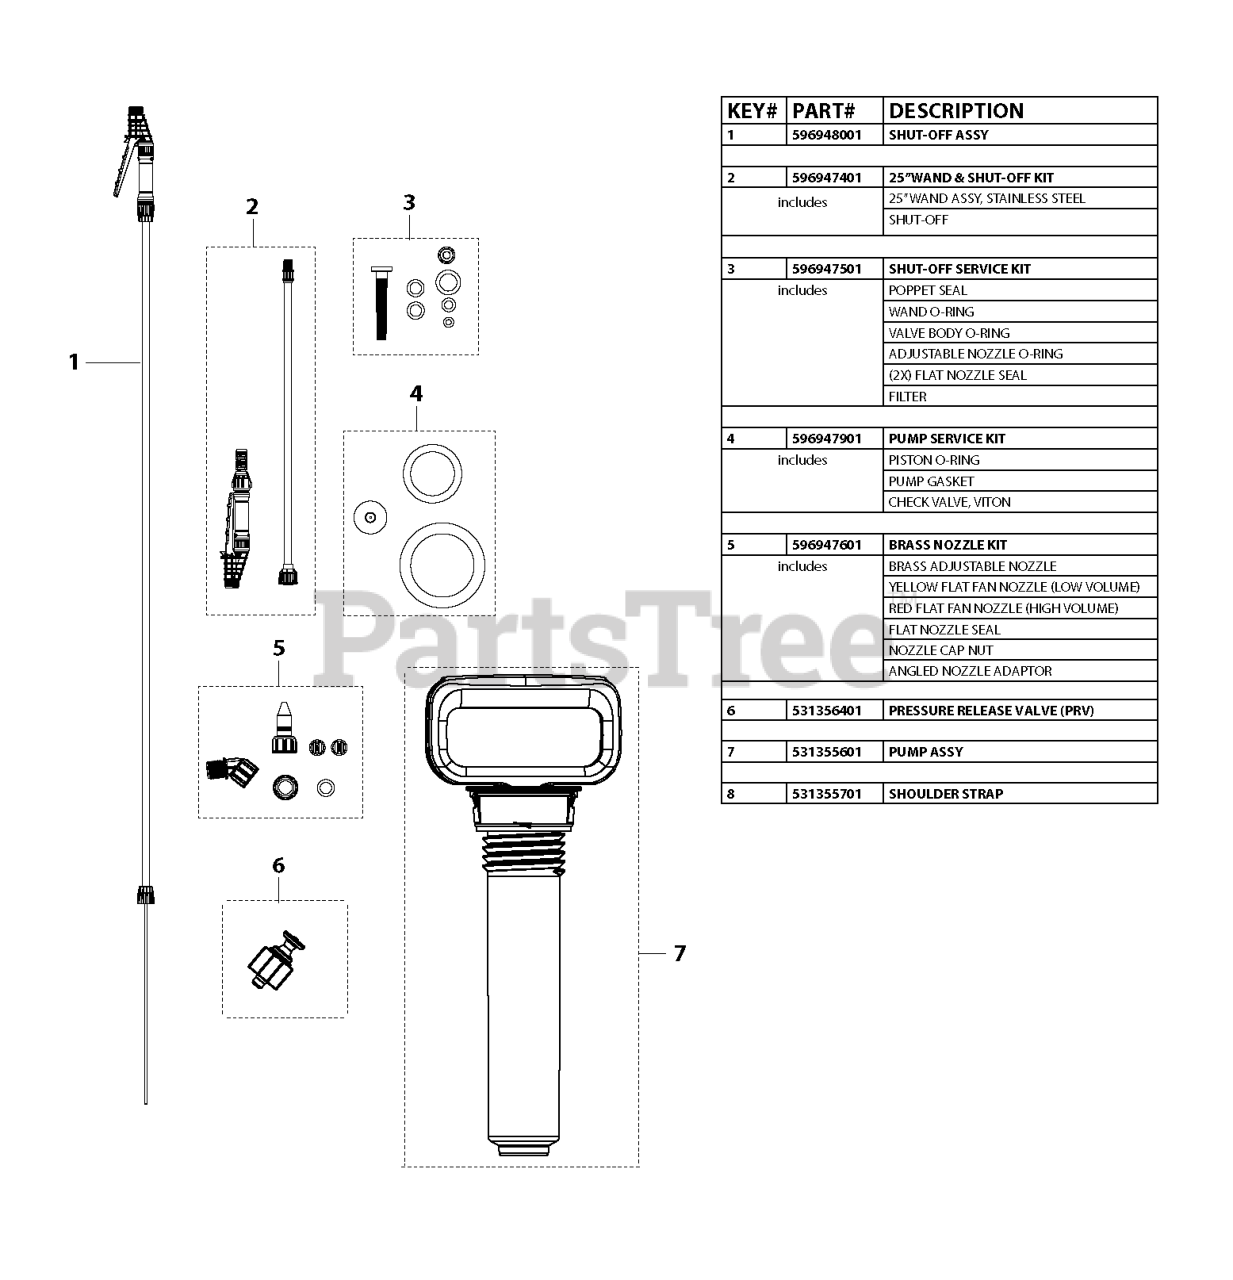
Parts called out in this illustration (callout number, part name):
1	2G SPRAYER SHUTOFF/HOSE ASSY
2	SPRAYER WAND/SHUTOFF KIT
3	SPRAYER SHUTOFF SERVICE KIT
4	2G SPRAYER PUMP KIT
5	SPRAYER NOZZLE KIT
6	PRESSURE RELEASE VALVE.
